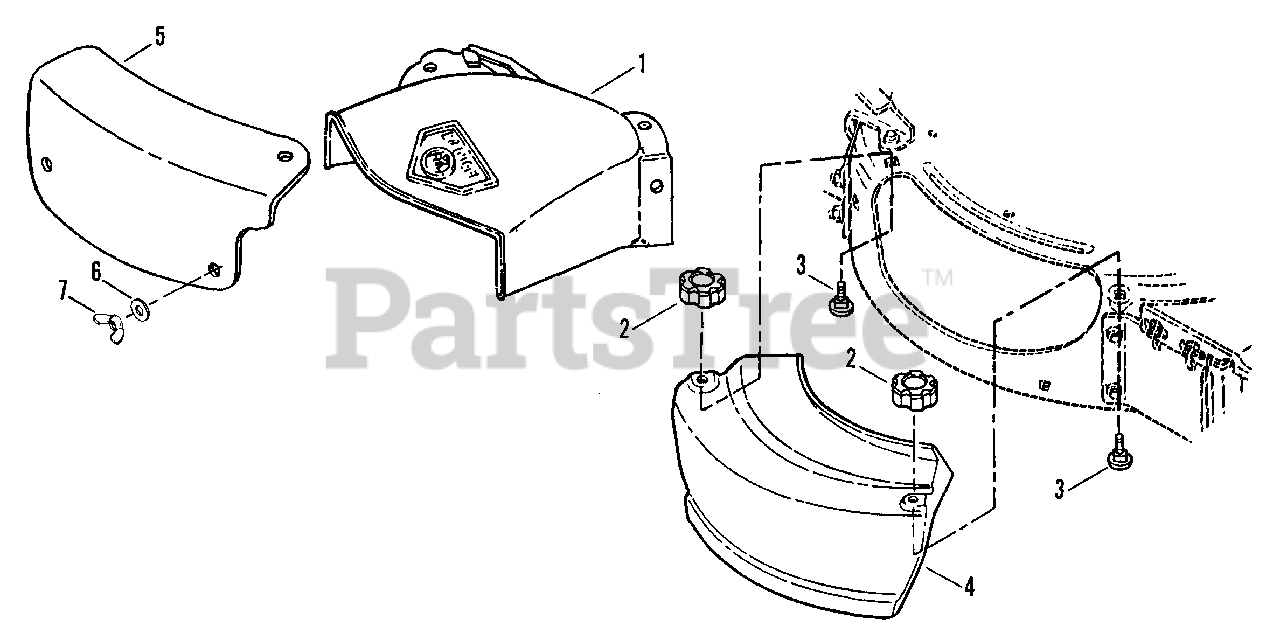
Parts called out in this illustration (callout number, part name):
1	ASSEMBLY,
2	KNOB, Fluted, 5/16-18 Thread
3	BOLT, 5/16-18 x 3/4" Short Neck Carriage, Grade 5
4	COVER, Recycling
5	COVER, Recycling
6	WASHER, 5/16 Flat
7	WING-NUT, 5/16-18 Nyloc
